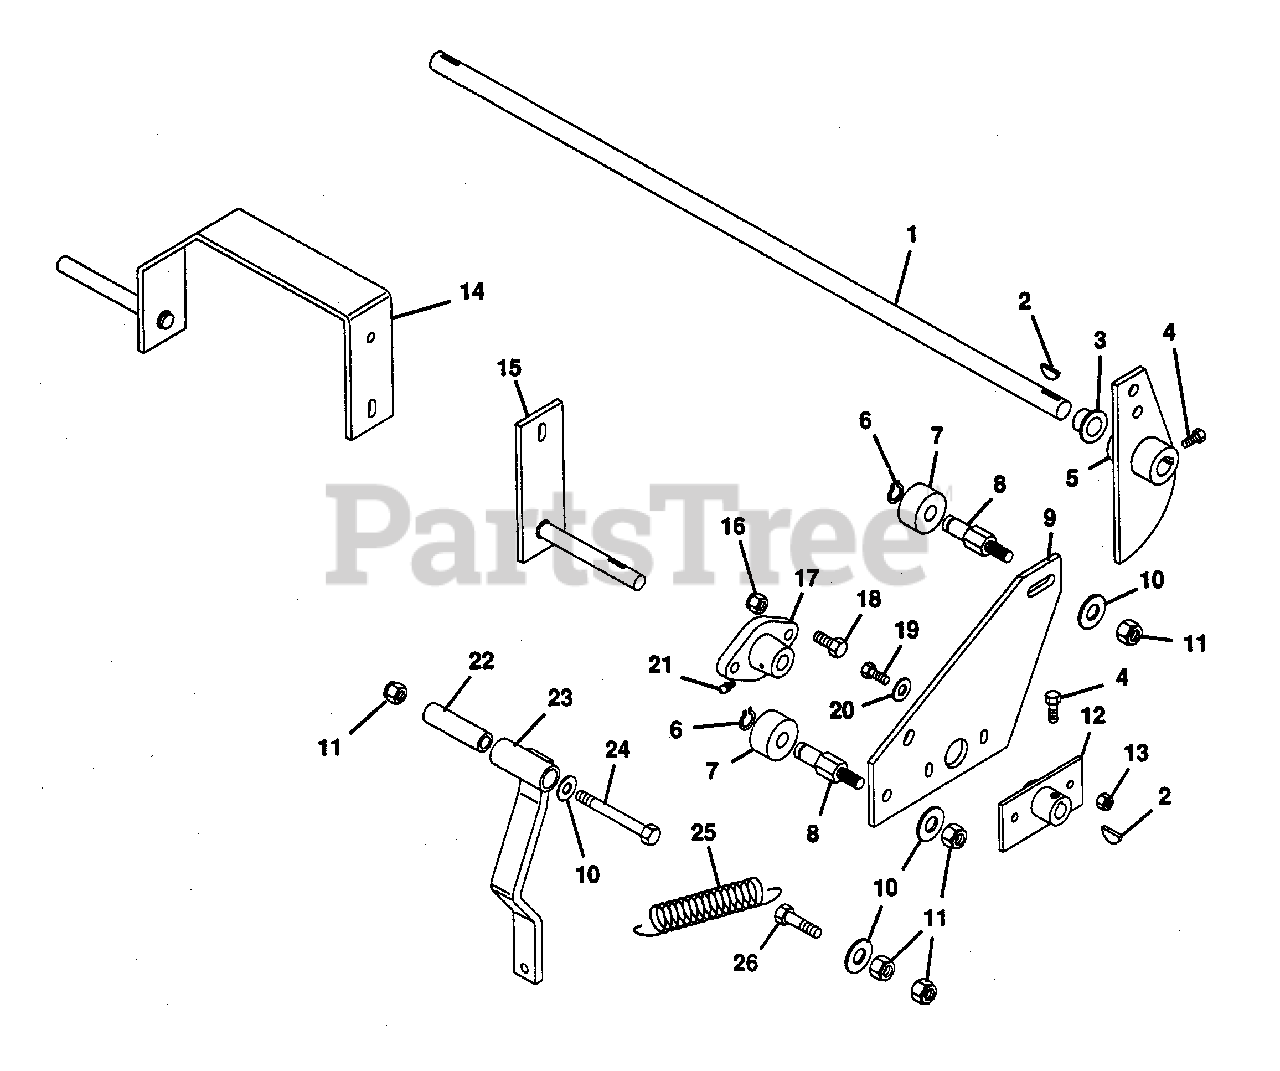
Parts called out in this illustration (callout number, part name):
1	Shaft, Speed Control Cam
2	Key, Woodruff .125x.75
3	Bush., Flg..630x1.00x.625 Ny.
4	Bolt, Hex 1/4-20x.50
5	Weldment, Control Cam
6	Ring, Retaining .500 Shaft
7	Roller, Nylon
8	Pin, Roller
9	Arm, Speed Control
10	Washer, Flat .406x.812x.065
11	Nut, Lock 3/8-16
12	Weldment, Neutral Adj.
13	Nut, Lock 1/4-20
14	Weldment, Pump Control R.H.
15	Weldment, Pump Control L.H.
16	Nut, Lock 5/16-18
17	Bushing, Flanged Support
18	Bolt, Hex 5/16-18x.75
19	Bolt, Hex 1/4-20x.750
20	Washer, Flat .281 x.625x.065
21	Fitting, Lube 114-28
22	Bush., St..385x.610x1.80 Stl.
23	Weldment, Detent Strap
24	Bolt, Hex 3/8-16x2.75
25	Spring, Ext. LE-063F-5
26	Bolt, Hex 3/8-16x1.50
